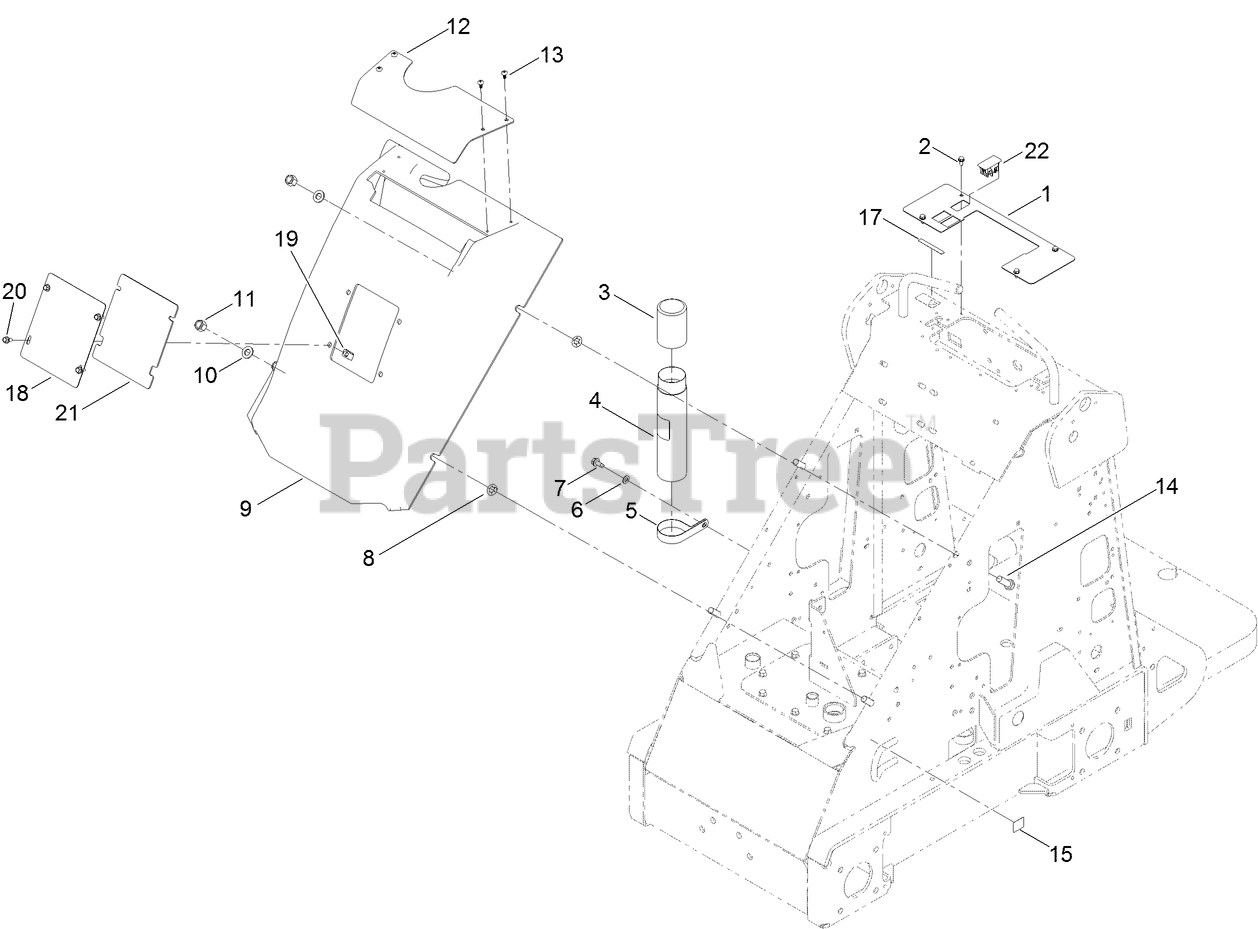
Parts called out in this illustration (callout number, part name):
1	PLATE-COVER
2	SCREW-HWH
3	CAP-HOUSING
4	TUBE-MANUAL
5	CLAMP-R
6	WASHER-PLAIN
7	SCREW-HWHTF
8	NUT-PUSH
9	HOOD-EDINGO
10	WASHER-FLAT
11	NUT-LOCK, NI
12	HOOD-TOP, EDINGO
13	SCREW-SEAT, SWITCH
14	SCREW-HH
15	DECAL-TIEDOWN
17	DECAL-WARNING
18	EDINGO-HOOD, COVER
20	SCREW-HEAD, FLANGE
21	FOAM-ACCESS, FUSE
22	PLUG-HOLE, CARLING
